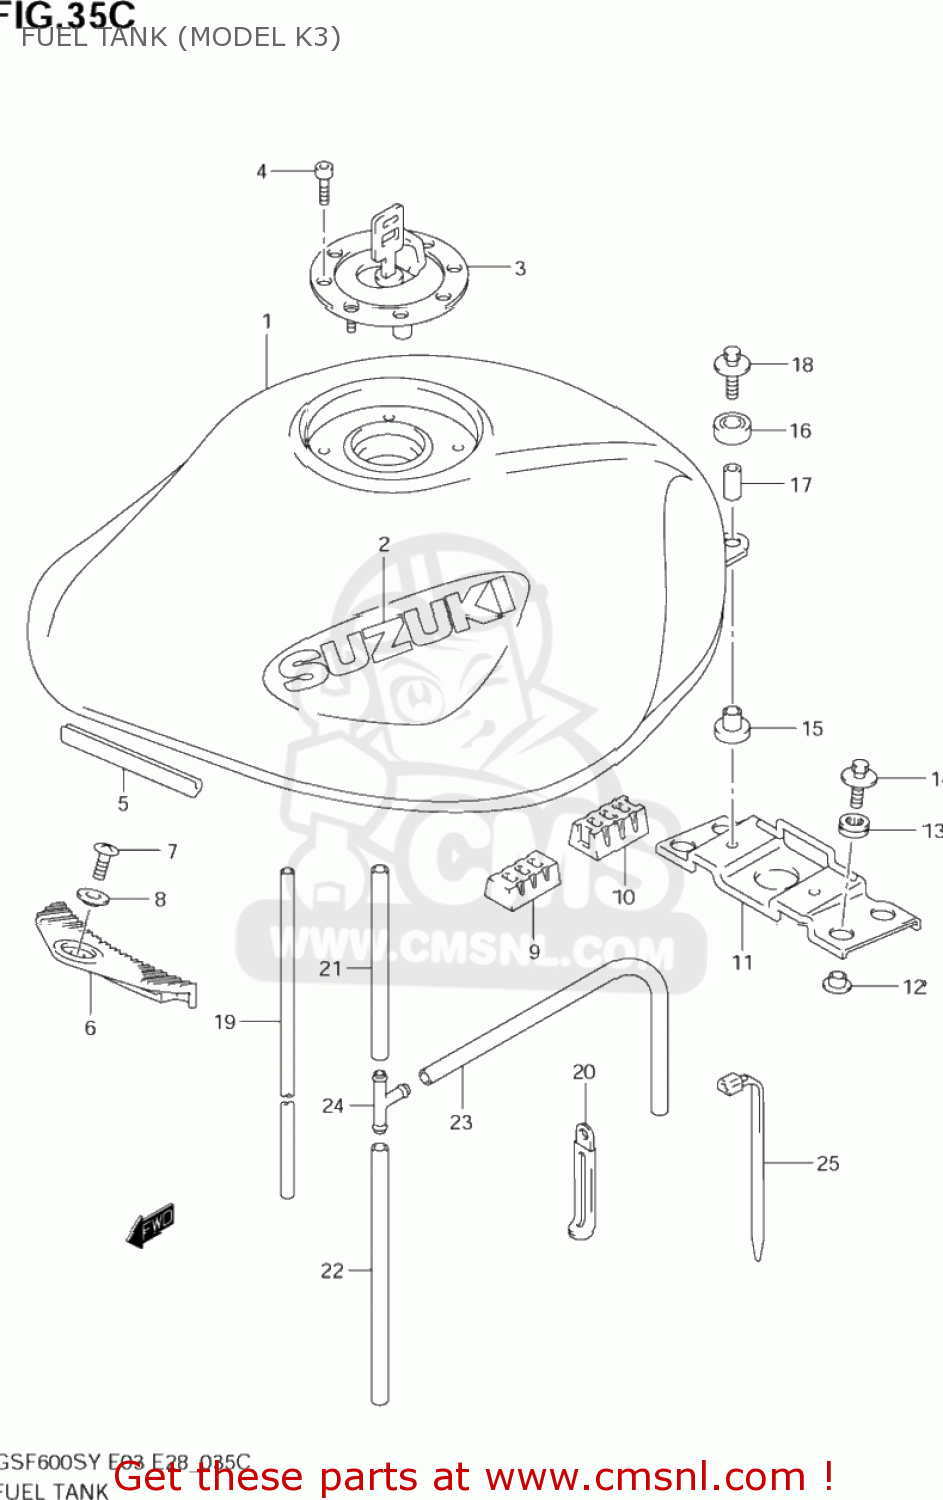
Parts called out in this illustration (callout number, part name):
1	TANK ASSY,FUEL(BLUE)
2	EMBLEM
3	CAP SET,FUEL TANK
4	BOLT(5X20)
5	MOLDING
6	CUSHION,FUEL TANK FR
7	SCREW
8	WASHER
9	CUSHION,SUPPORT(50X25X32)
10	CUSHION,TANK SIDE
11	BRACKET,FUEL TANK RR
12	WASHER
13	CUSHION
14	BOLT(6X25)
15	CUSHION
16	CUSHION,FUEL TANK RR
17	SPACER(6.5X9X18)
18	BOLT(6X30)
19	HOSE(7X11X2000)
20	CLAMP(L:97)
21	HOSE(5X8.2X600)
22	HOSE(5X8.2X600)
23	HOSE(5X8.2X600)
24	JOINT,3 WAY
25	CLAMP(L:125)
